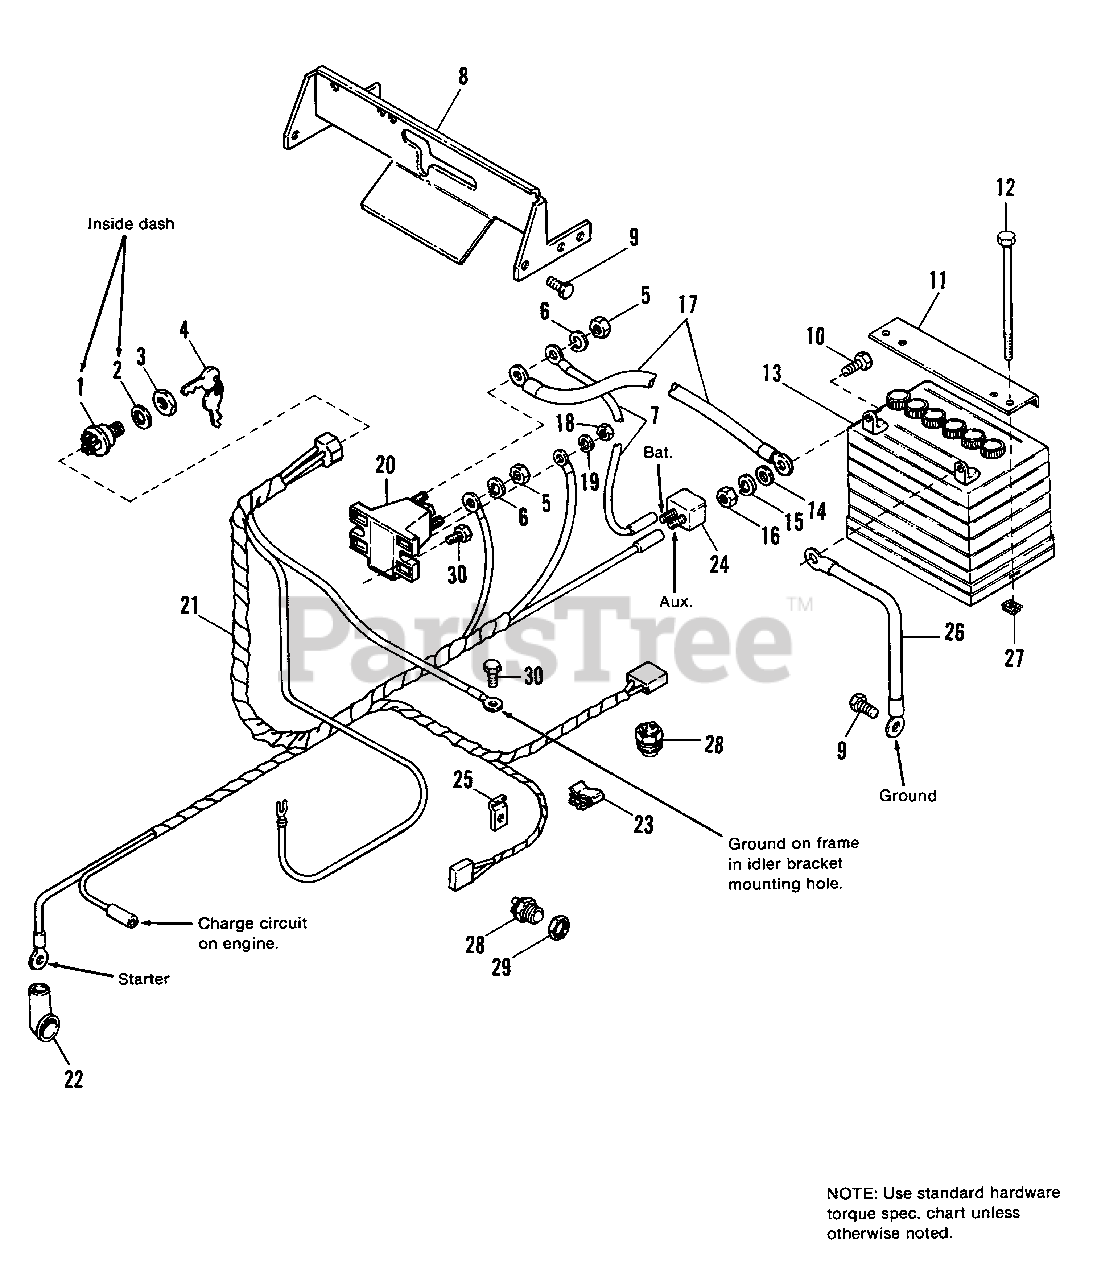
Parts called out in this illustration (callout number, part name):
1	SWITCH, Ignition
2	LOCKWASHER, Internal Tooth, 5/8
3	NUT, 5/8-32
5	NUT, Hex, 5/16-18
6	LOCKWASHER, 5/16
8	QUADRANT, Shift
9	SCREW, Taptite, 1/4-20 x 3/8
10	CAPSCREW, Hex, 1/4-20 x 3/4
11	CLAMP, Battery
12	CAPSCREW, Hex, 1/4-20 x 7-1/2
13	BATTERY SERVICE KIT
14	WASHER, 1/4
15	LOCKWASHER, 1/4
16	NUT, Hex, 1/4-20
18	NUT, Hex, #10-32
19	LOCKWASHER. Ext., #10
20	SOLENOID
21	HARNESS, Wiring
22	COVER, Terminal
23	CLIP, Speed
24	CIRCUIT BREAKER
27	NUT, Retainer, 1/4-20
28	SWITCH, Interlock
29	LOCKNUT, 9/16-18
30	SCREW, Taptite, 1/4-20 x 5/8
